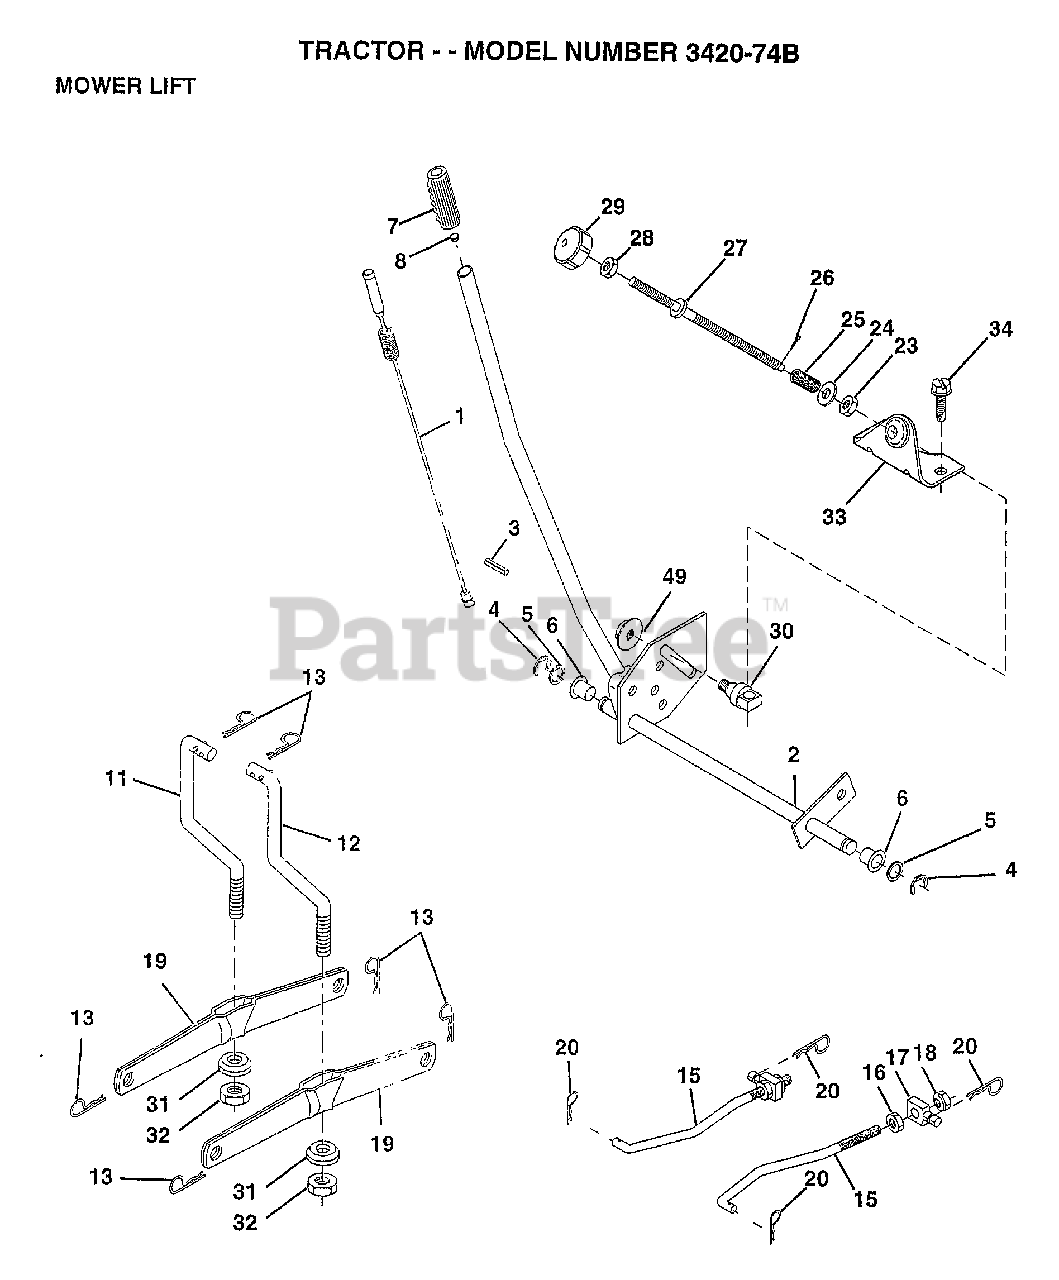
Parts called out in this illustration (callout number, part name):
1	WIRE ASM W.SPRING
2	"SHAFT ASM LIFT,LH"
3	PIN GROOVE
5	WASHER
6	NYLON BEARING
7	GRIP
15	LINK.FRONT
16	NUT
17	TRUNION
18	NUT.LK.W/WSH.1/2.
19	ARM SUSP REAR
20	RETAINER.SPRING
23	NUT T
24	WASHER
25	SPRING.COMP.INF.H
27	ROD.ADJ.LIFT
28	NUT
29	KNOB INF 3/8-16
30	TRUNNION
31	BEARING PVT LH
32	NUT.CROWNLOCK.3/8
49	NUT.HXFLG.LOCK.
50	NUT PUSH M
